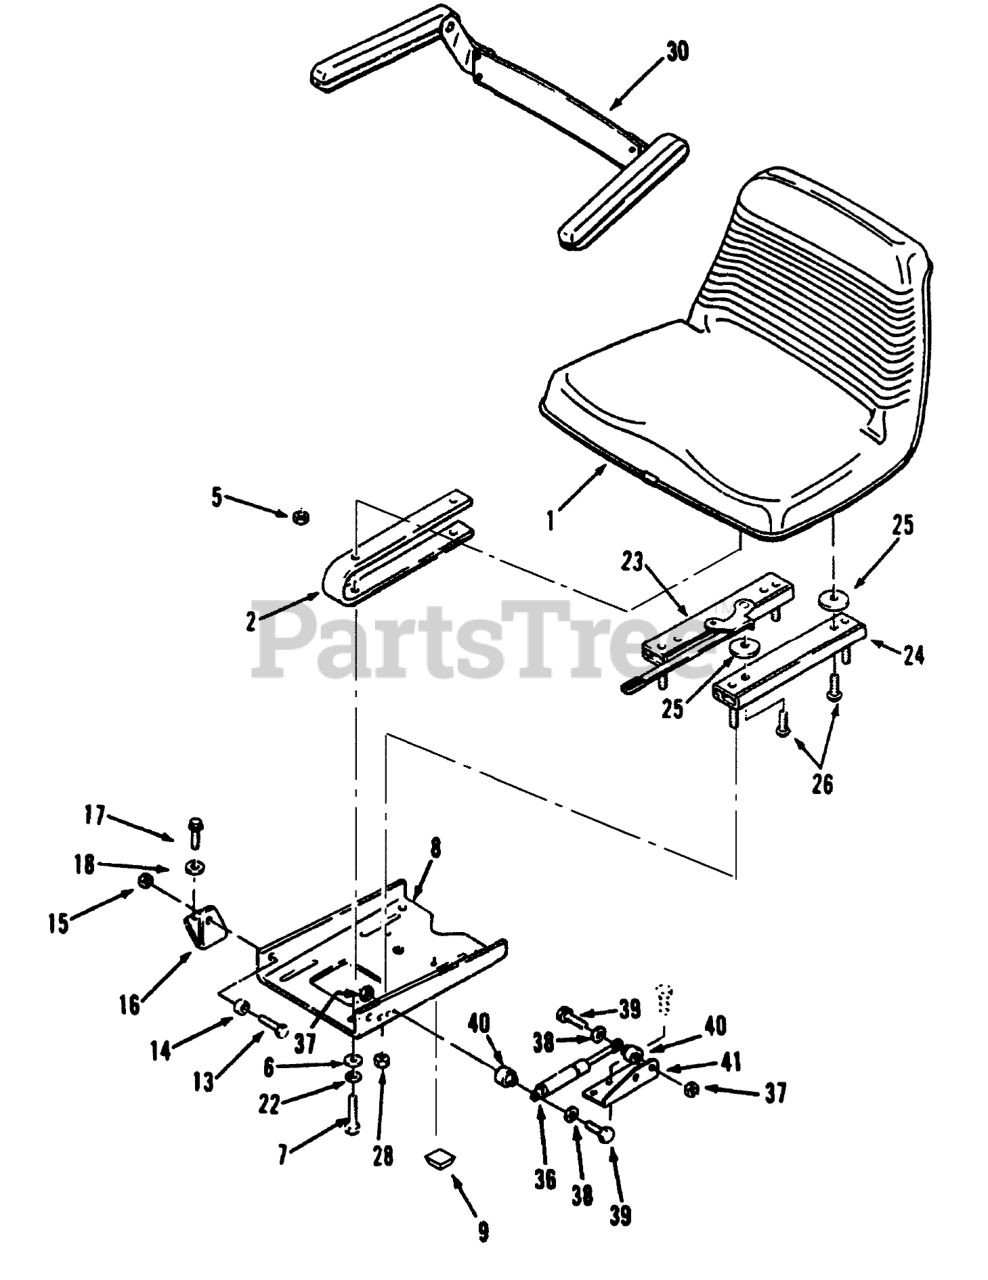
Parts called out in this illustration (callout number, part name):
1	Seat
2	Seat Spring
5	NUT-HEX
6	WASHER-PLAIN
7	SCREW-HH
8	Plate-SeatPivot
9	BUMPER SJ5514 BLACK
13	HHCS
14	BUSHING
15	NUT-LOCK, NI
16	Bracket-Pivot RH
17	Bolt
18	WASHER 5/16 SAE
22	WASHER-LOCK
23	Adjuster-Seat
24	ADJUSTER-R.H. SEAT
25	SPACER-NYLON
26	Screw
28	NUT-HEX
30	KIT-ARMREST
34	NUT-LOCK, NI
36	GAS SPRING
37	NUT-LOCK, NI
38	WASHER-FLAT
39	SCREW-HH
40	SPACER
41	BRACKET-CYLINDER R
